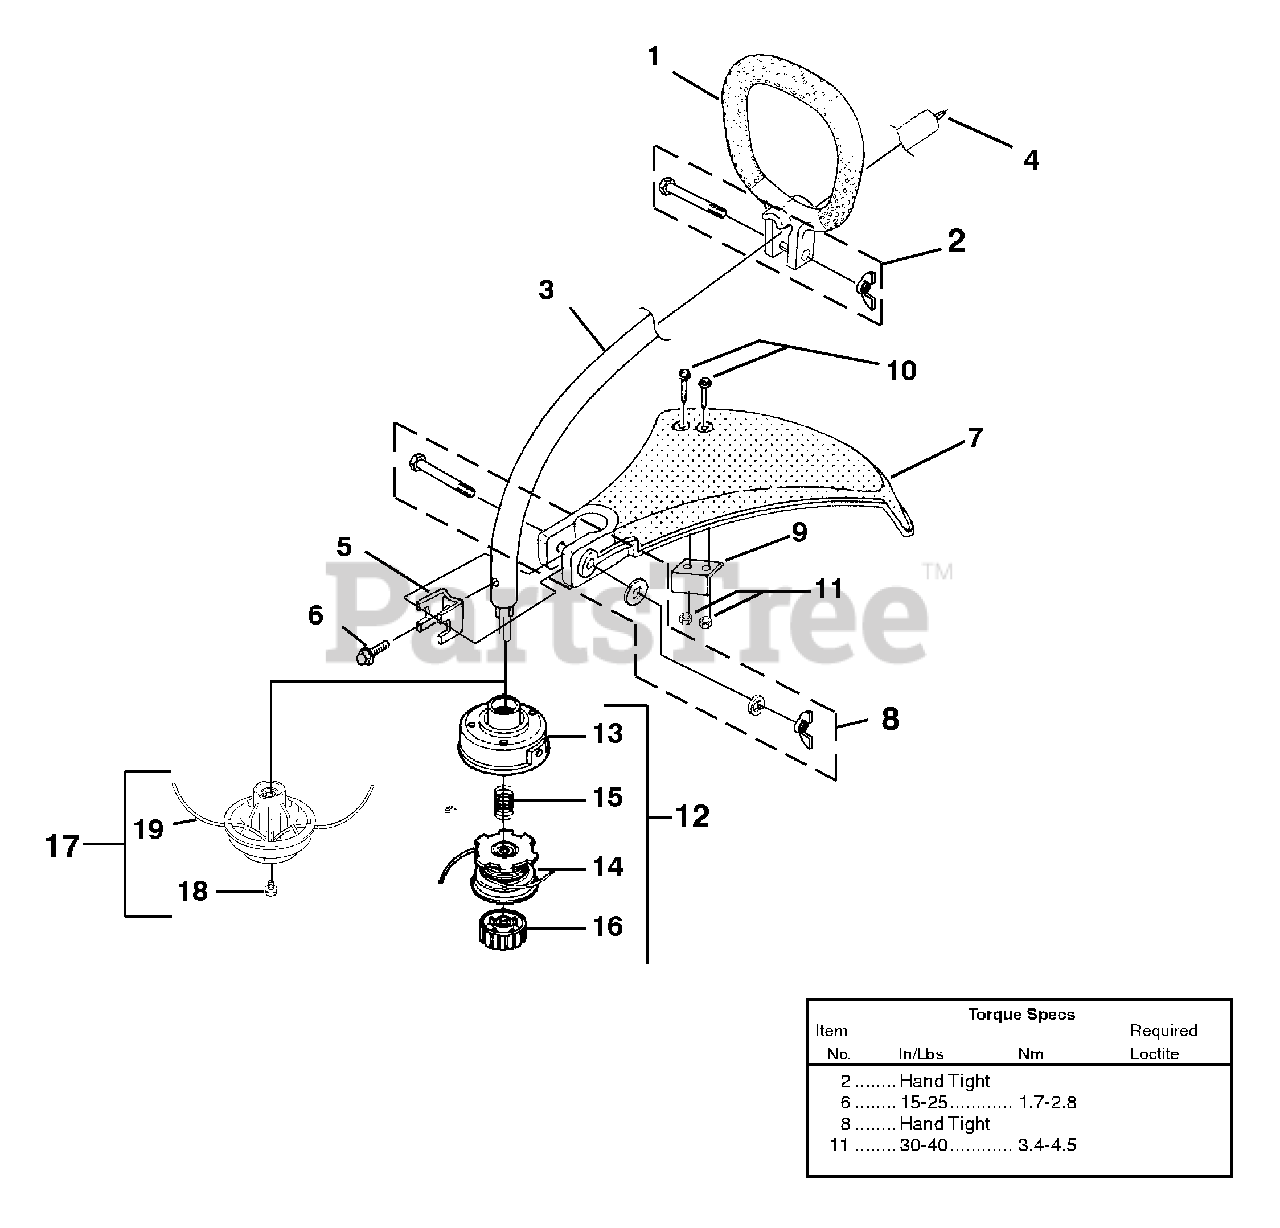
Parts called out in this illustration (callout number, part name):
1	HANDLE ASSY.-Front
2	FASTENER PARTS KIT
3	DRIVESHAFT HOUSING ASSY.
4	SHAFT-Flexible
5	CLAMP
6	SCREW-T.F. Hex Hd. (10-32 X 3/8")
7	DEFLECTOR & BLADE KIT (55 Deg.)
8	FASTENER PARTS KIT
9	BLADE-Cut-Off
10	SCREW-Mach. Hex Hd. (10-24 X 7/8")
11	NUT-Hex (10-24)
12	STRINGHEAD-Complete
13	HOUSING & EYELET (Dual Line)
14	SPOOL & STRING (.080" Line)
15	SPRING-Compression
16	RETAINER-Spool (RH Thread, Black)
17	STRINGHEAD-Pro-Cut w/line
18	SCREW-Stringhead Retainer
19	LINE-Replacement
